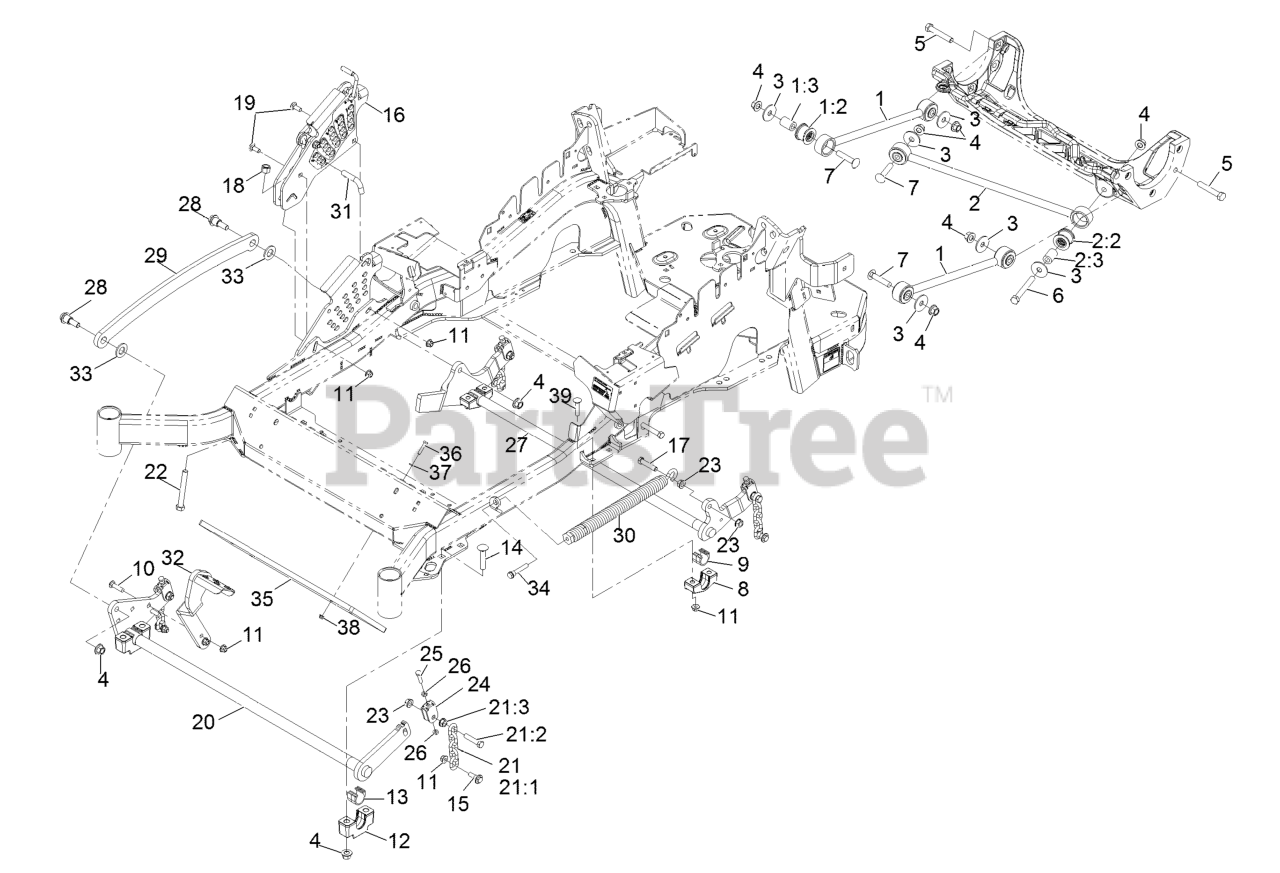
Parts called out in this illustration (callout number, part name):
1	DECK STRUT ASM
1:2	BUSHING-SUSPENSION, RUBBER
2	PANHARD ROD ASM
2:2	BUSHING-SUSPENSION, RUBBER
3	WASHER-THRUST
4	Nut-Lock 1/2-13
5	SCREW-HH
6	SCREW-HH
7	SCREW-CARR
9	BEARING-CROSS SHAFT, REAR
10	SCREW-CARR
11	NUT-HF, NI
12	SUPPORT-CROSS SHAFT, BEARING
13	BEARING-CROSS SHAFT, FRON
14	Bolt-Carriage 1/2-13 X 2 1/2 Spl Neck
15	SCREW-SHOULDER, HHF
16	HOC ASM
17	SCREW-HH
18	NUT-LOCK, NI
19	BOLT-CARR
21	DECK LIFT CHAIN ASM
21:1	CHAIN-LIFT, DECK
21:2	SCREW-HH
22	BOLT-TAP
24	YOKE-ADJUST, DECK
25	SCREW-HH
26	NUT-JAM
27	LIFT-DECK, REAR
28	SCREW-SHOULDER, HHF 1/2-13 X 1.12
29	LINK-LIFT, DECK
30	SPRING-EXTENSION
31	PIN-HOC
32	LEVER-FOOT
33	WASHER-FLAT
34	BOLT-SHOULDER
35	WEIGHT,TOE BOARD
36	SCREW-HH
37	WASHER-FLAT
39	SCREW-CARR
